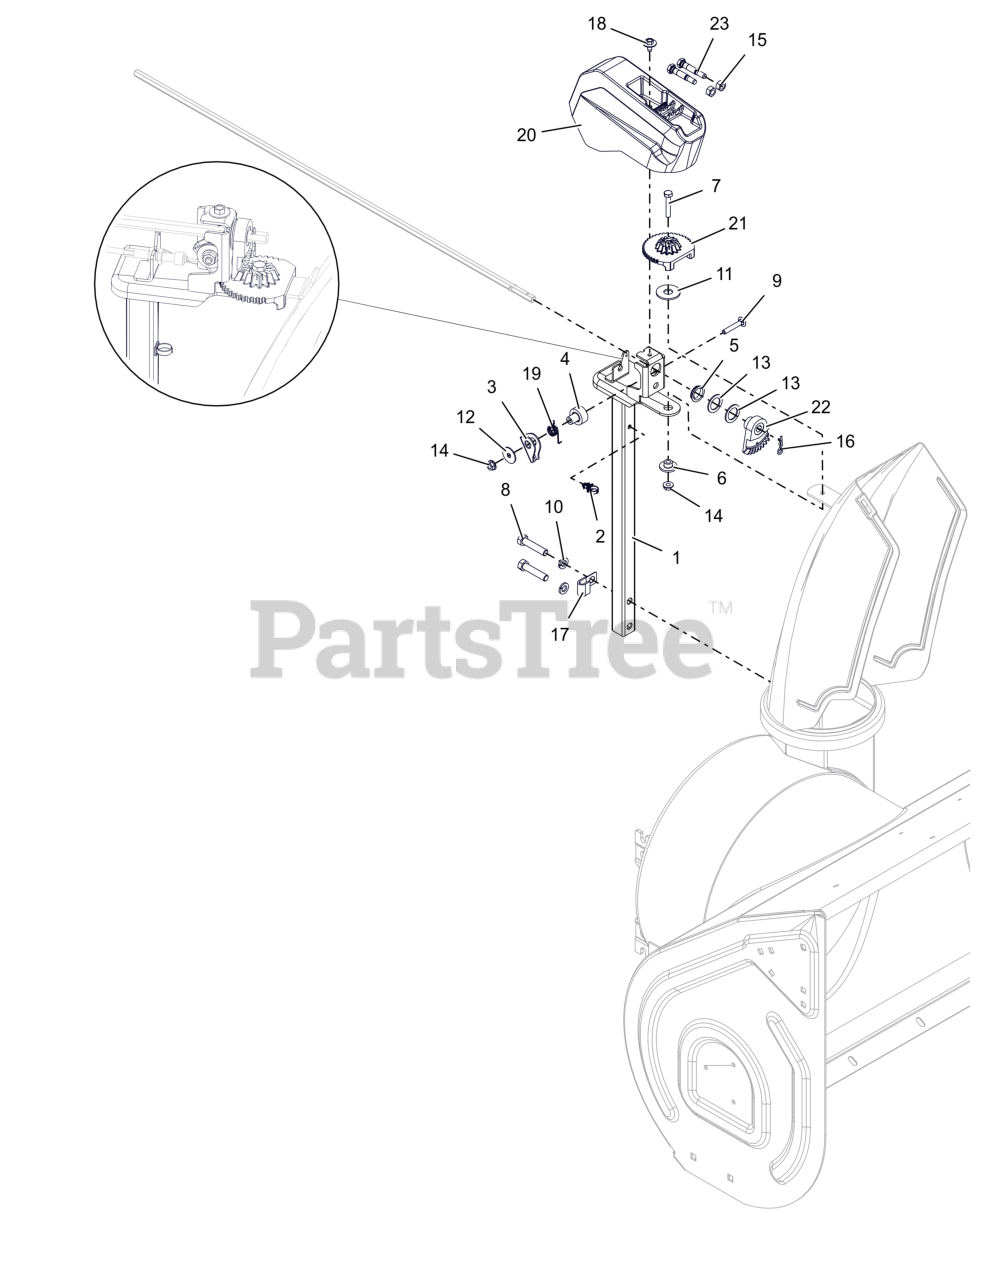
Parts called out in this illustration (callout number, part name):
1	PEDESTAL, CHUTE - QUICK STICK
2	CLIP, CABLE GUIDE
3	ARM, LOCKING
4	BUSHING, LOCK ARM
5	BUSHING, POLYLINER-.75 SNAPIN
6	BSHG-FLG .265X.477X.375X1.00
7	BLT, HEX .25-20X1.50 G5 ZCC
8	BLT, HEX .38-16X1.75 G5 ZCC
9	BLT, RHSN .25-20X1.50 G5 ZCC
10	WSHR,LK-REG .375X.094 ZCC
11	WSHR-FLT-NYL .515X1.375X.093
12	WSHR,FLT .281X1.000X.063 ZCC
13	WSHR, FLT .754X1.125X.062 ZCC
14	NUT-LK-CTR-FLG .25-20 ZC120
15	NUT,LK-CTR .31-18 GA ZCC
16	PIN, HAIR #213 .08X1.19 ZCC
17	J-CLAMP
18	SCR, TAP .25-20X.50 LG HWH ZCC
19	SG-TORS
20	COVER, CHUTE PEDESTAL
21	GEAR- CHUTE-LOCKING
22	GEAR- CHUTE-ACTUATION
23	SHEAR BOLT SERVICE ASSEMBLY (INCLUDES NUT)
